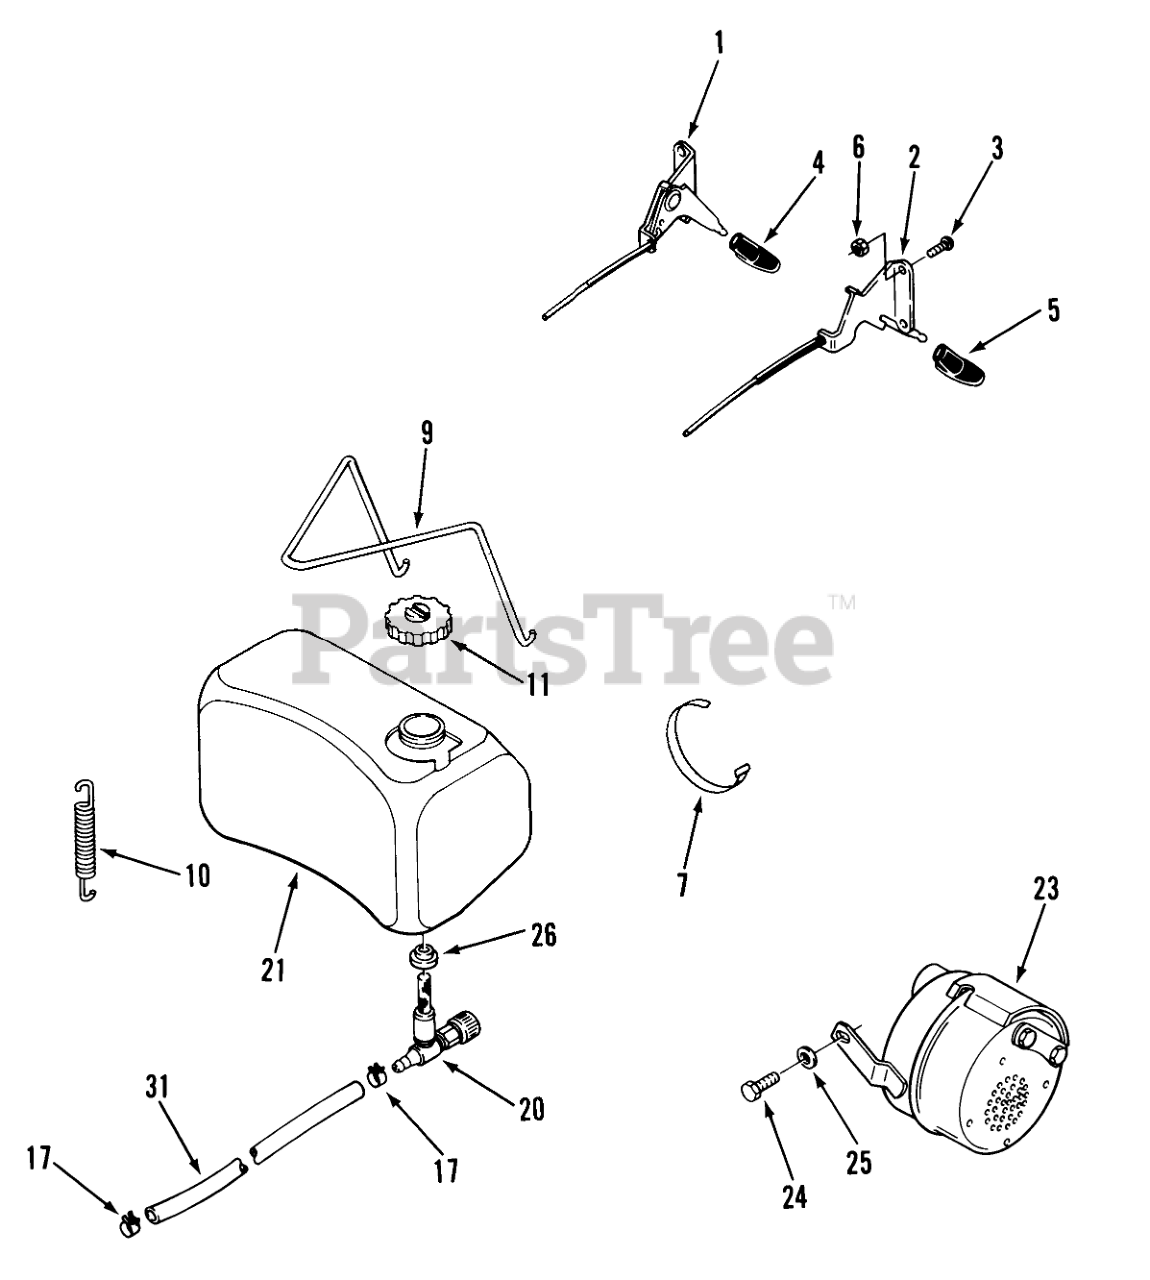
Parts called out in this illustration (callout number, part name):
1	CONTROL-THROTTLE
2	CONTROL-CHOKE
2	CONTROL THROTTLE
3	Screw
4	KNOB-THROTTLE
5	KNOB-CHOKE
6	Nut
7	Cable Tie
9	Hold Down Wire
10	SPRING-EXTENSION
11	CAP-GASOLINE
17	Clamp
20	VALVE-FUEL
21	Fuel Tank Assy
23	ASSY-MUFFLER
24	Bolt
26	BUSHING
31	Hose
31	Fuel Hose 14.5 in. (36.8 cm) B-115 Only
